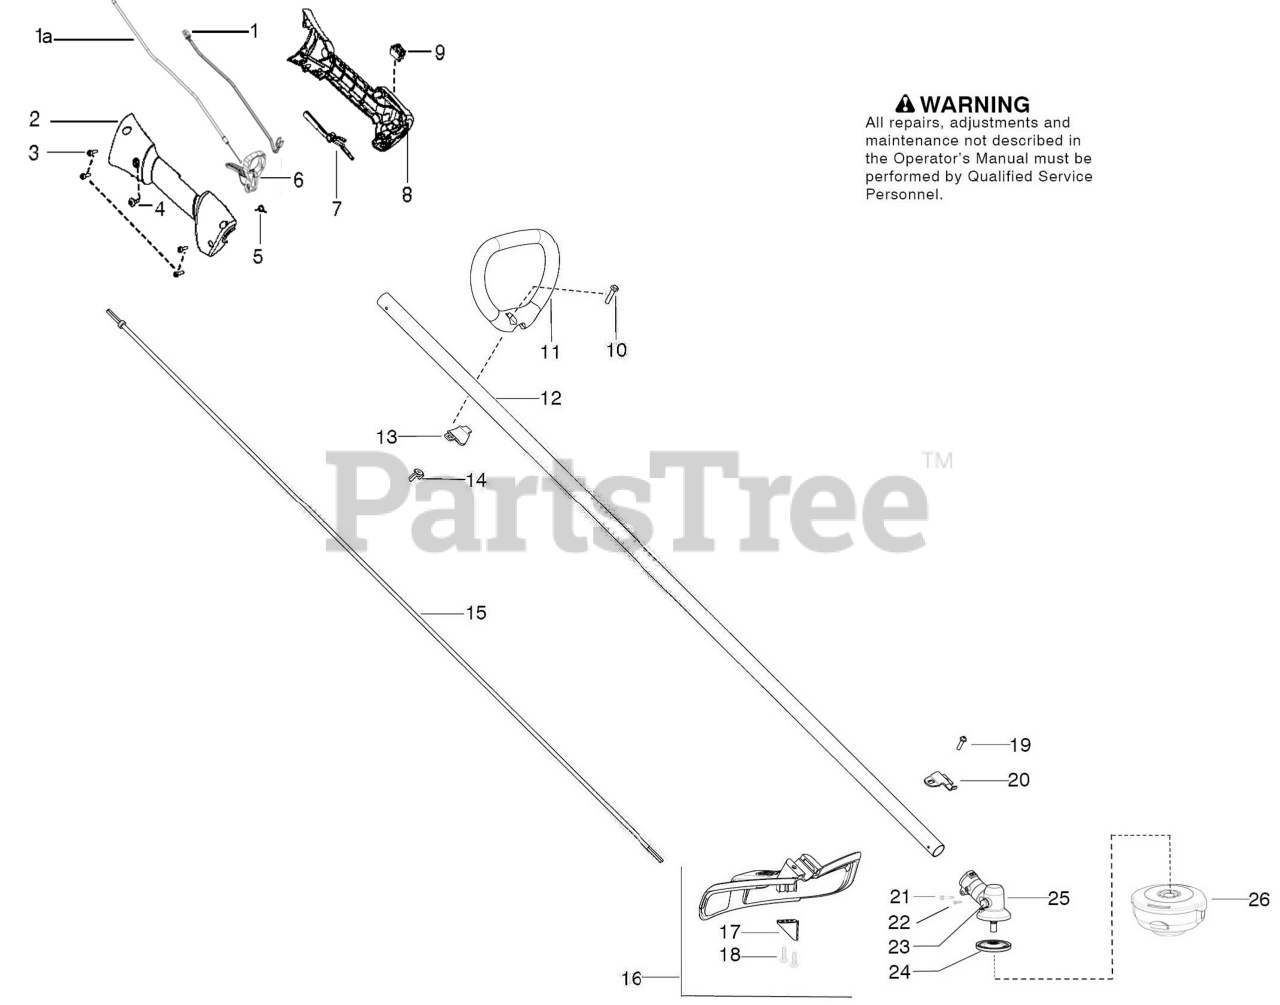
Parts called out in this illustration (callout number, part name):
1	CABLE SHORT CIRCUIT HND
2	HSG THROTTLE RIGHT HVA
5	SPRING TRIGGER
6	TRIGGER THROTTLE HVA ORANGE
7	THROTTLE LOCKOUT HVA ORANGE
8	HSG THROTTLE LEFT HVA
9	SWITCH
10	BOLT, TYPE 2
11	HANDLE ASSIST SOFT
13	CLAMP ASSIST HANDLE
14	WINGNUT, TYPE 2
15	FLEXSHAFT 57"
16	KIT STRAIGHT SHIELD
17	Limiter - Line
18	SCREW 10-14X3/4 PLASTITE
19	SCREW 1/4-20
20	BRACKET SHIELD STRAIGHT SHAFT
21	SCREW 8-32 X 16.51
22	SCREW 8-32 X 16.51 TT SC TRX
23	PLUG GREASE 9MM
24	DRIVE DISC
25	ASSY GEARBOX
26	T25 TRIM HEAD 10MM LH
